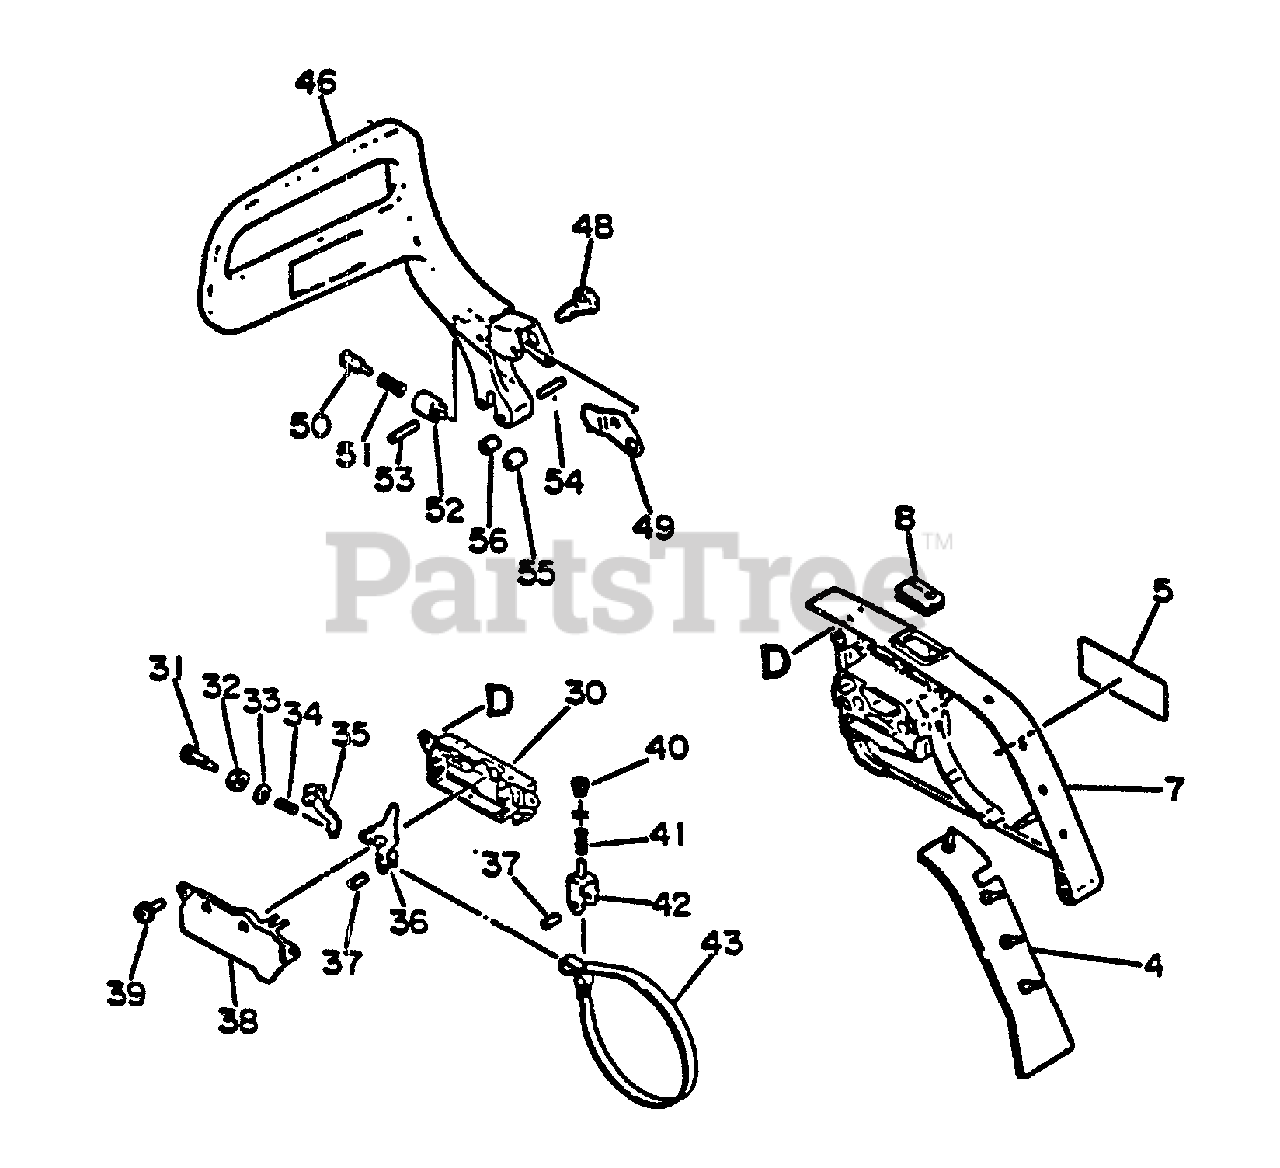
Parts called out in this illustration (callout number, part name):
5	LABEL - ECHO
7	GUARD, SPROCKET
8	CHAIN BRAKE ASSY
30	COVER, BRAKE
34	SPRING, BRAKE
35	STOPPER, BRAKE
36	LEVER, BRAKE
37	PIN - SPRING -- 4X10
38	COVER, BRAKE
39	SCREW - 4X10
42	ADJUSTER, BRAKE BAND
43	BAND, BRAKE
46	BRAKE LEVER ASSY
55	SPACER
56	SPACER
